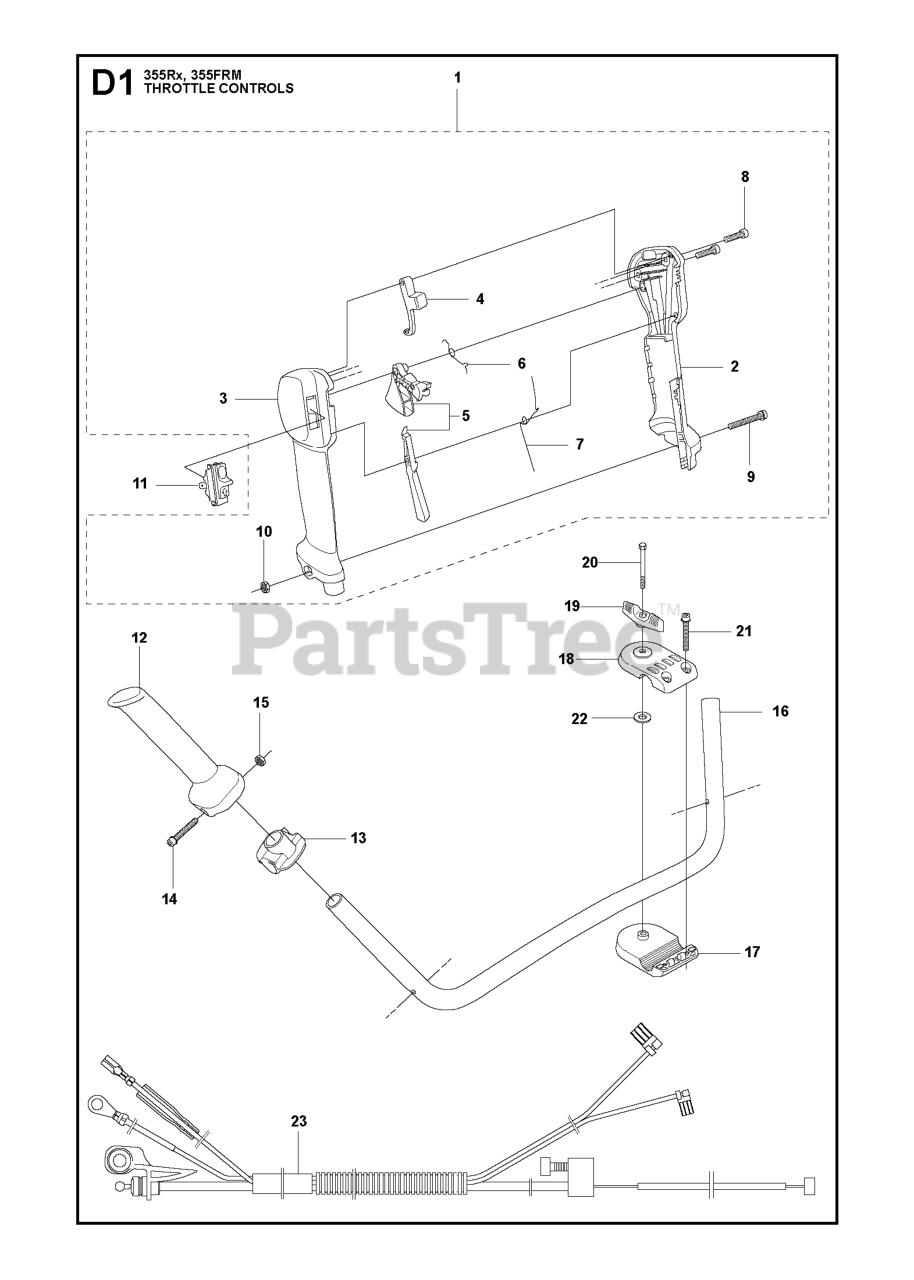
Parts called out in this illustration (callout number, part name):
1	THROTTLE HANDLE ASSY
2	HANDLE HALF RIGHT
3	HANDLE HALF LEFT
4	LOCKOUT STARTER THROTTLE
5	THROTTLE CONTROL
9	SCREW
11	STOP BUTTON
15	NUT M6M M5
16	HANDLE
17	HANDLE HOLDER LOWER
18	HANDLE HOLDER UPPER
20	SCREW 6X70
23	WIRING ASSY SKOG
23	WIRING
